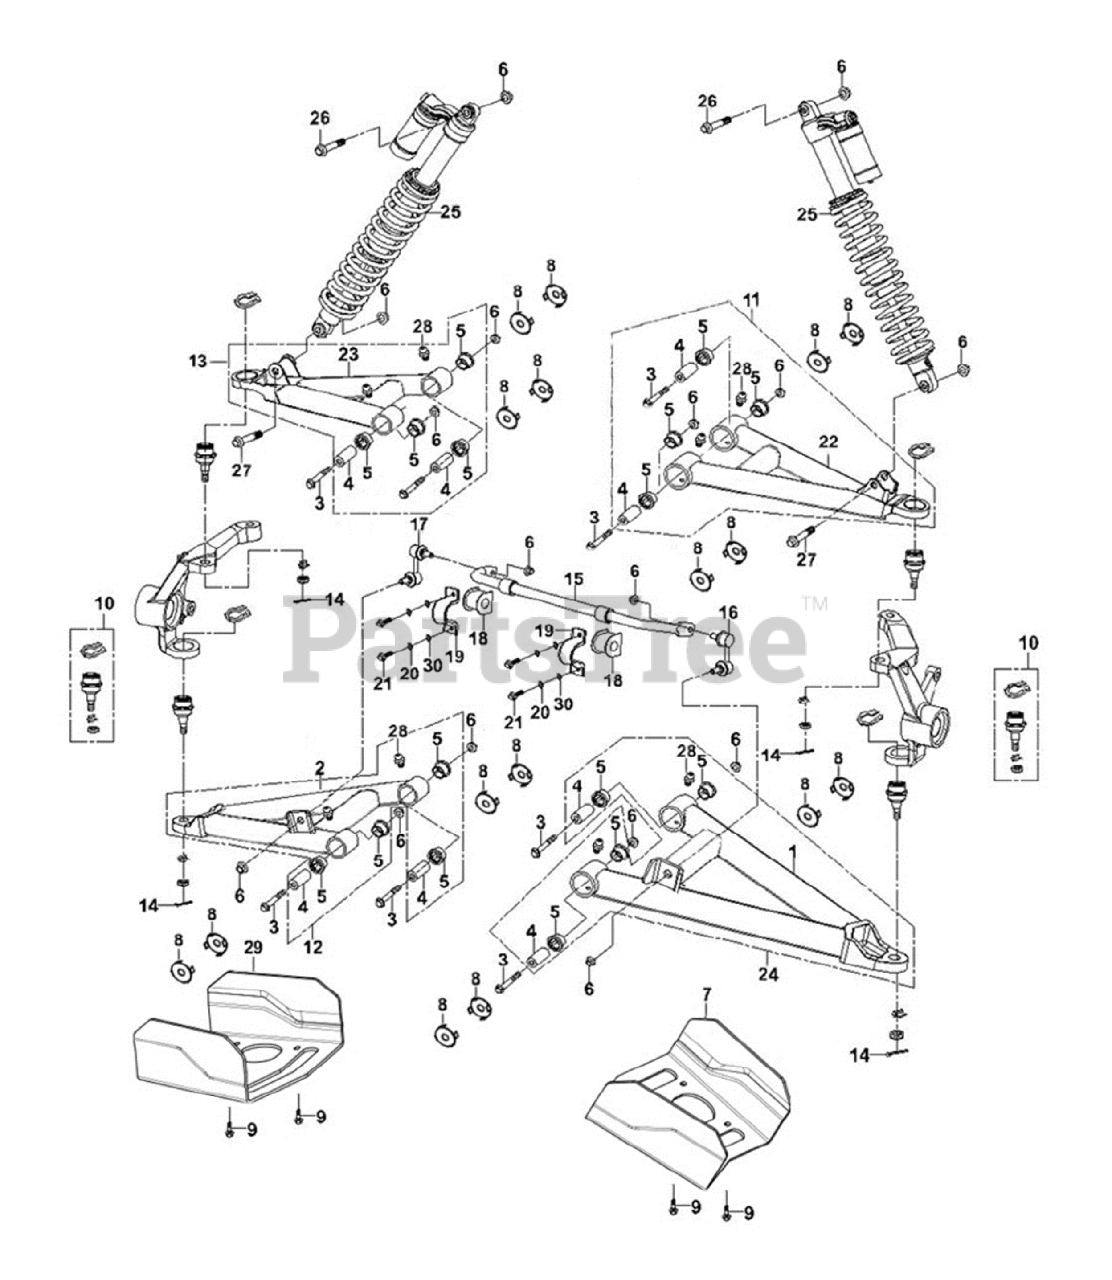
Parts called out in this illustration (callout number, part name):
1	Arm welding kit(front left Lower)
2	Arm welding kit(front right lower)
3	BOLT HExAGON FLANGE HEAD M10x1.25-80
4	Bush 10.3x 23x49.4
5	Bush 22x28
6	LOCK NUT M10x1.25
7	SHIELD CV - BASIC ?
8	BUSHING CAP ?
9	Cross Large Plate Head Screw M6x16
10	Universal Joint E
11	ARM ASSEMBLY - FRONT LEFT UPPER
12	ARM ASSEMBLY - FRONT RIGHT LOWER
13	ARM ASSEMBLY - FRONT RIGHT UPPER
14	Cotter pin 2.5x30
15	STABILIZER BAR - FRONT
16	ROD BALL KIT - RIGHT
17	ROD BALL KIT - LEFT
18	Cushion Bush 20x45,balancing lever
19	mounting cap,cushion rubber
20	Spring Washer-8
21	Hexagon Flange Bolt M8x20
22	Arm welding kit(front left upper )
23	Arm welding kit(front right Upper)
24	ARM ASSEMBLY - FRONT LEFT LOWER
25	FRONT SHOCK ABSORBER Q
26	Hexagon Flange BoltM10x1.25x55
27	Hexagon Flange BoltM10x1.25x55
29	SHIELD CV - BASIC II
